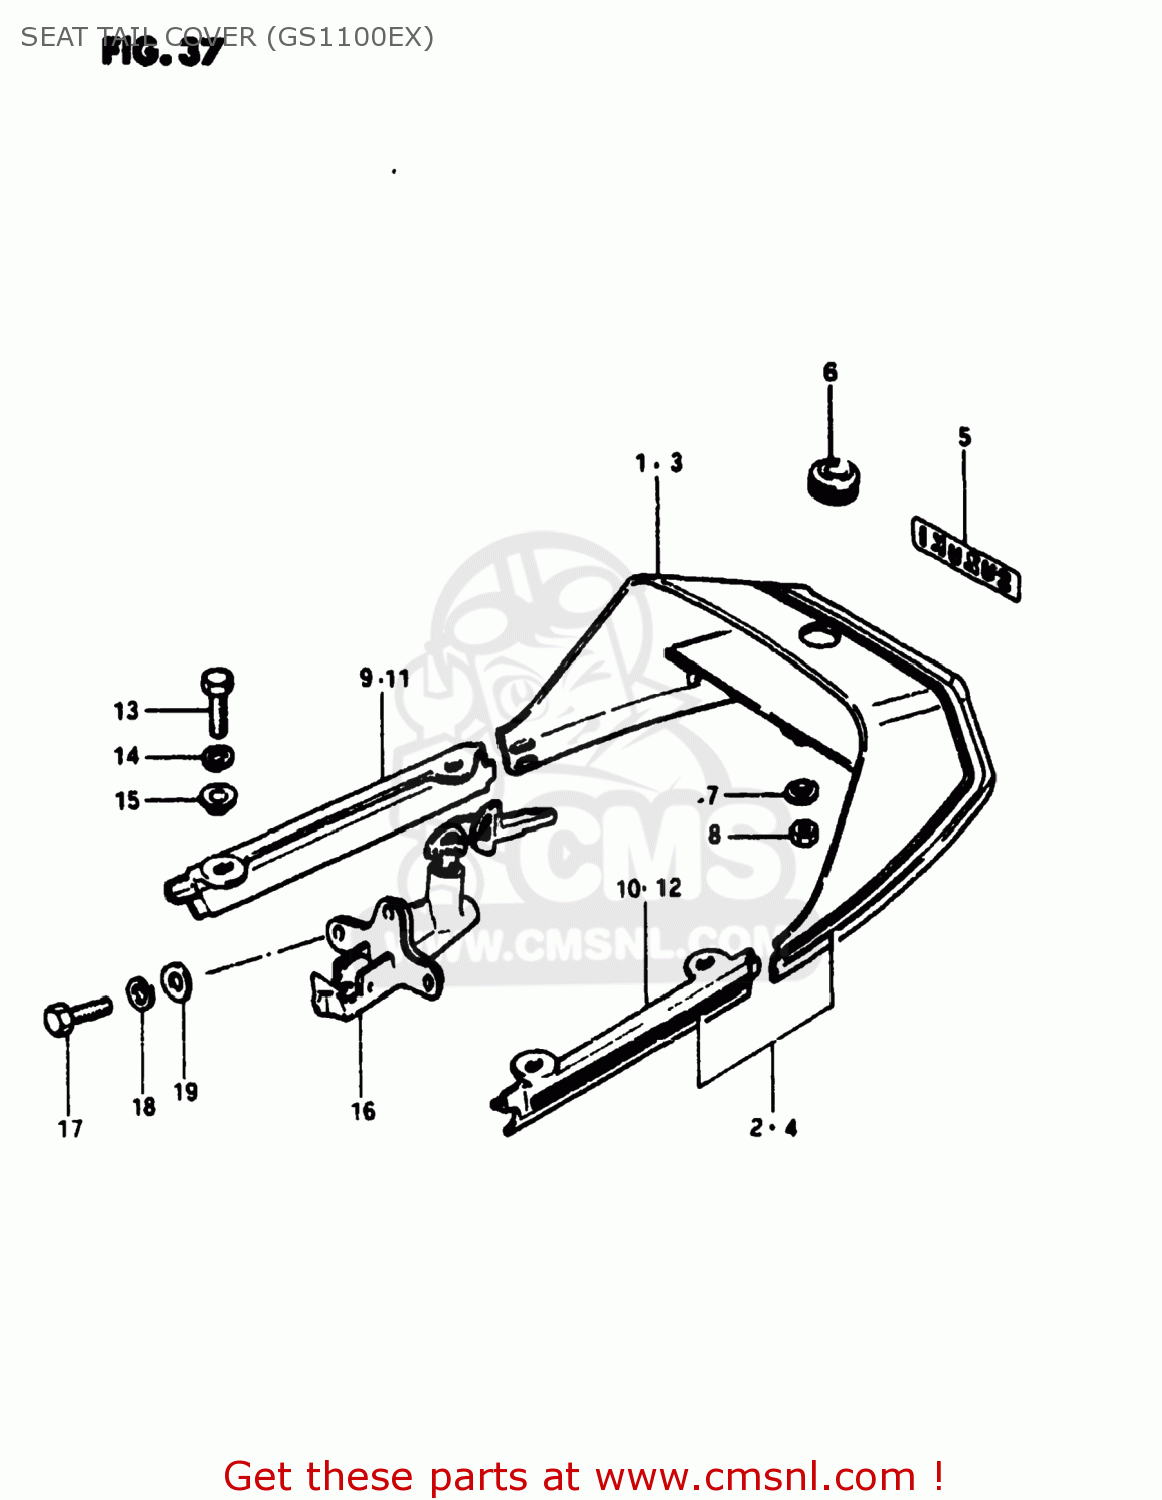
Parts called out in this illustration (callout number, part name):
1	COVER,SEAT TAIL
3	COVER,SEAT TAIL
4	TAPE SET
5	EMBLEM (GOLD/BLACK)
6	GROMMET,SEAT LOCK HOLE
7	WASHER
8	NUT 6MM
9	MOULDING, SEAT RH (BLACK)
10	MOULDING, SEAT LH (BLACK)
11	MOLDING,SEAT,R
12	MOLDING,SEAT,L
13	BOLT
14	LOCK WASHER
15	WASHER
16	LOCK SET
17	BOLT
18	LOCK WASHER
19	WASHER 6MM
